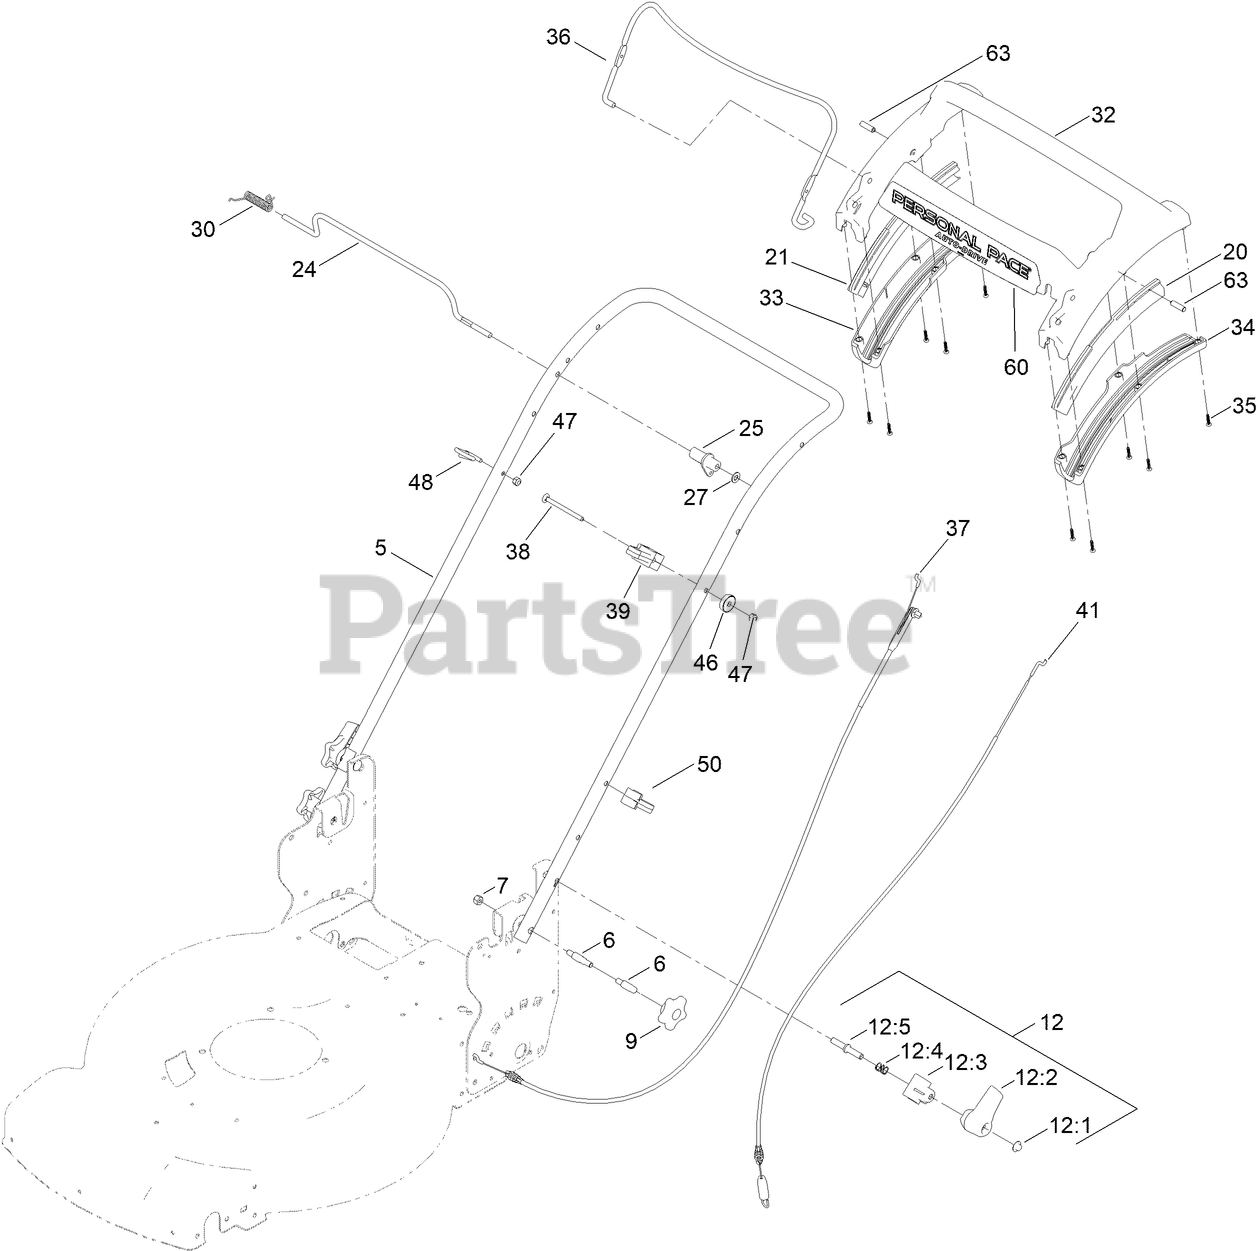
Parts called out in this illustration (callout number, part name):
5	HANDLE-CURVED
6	BOLT-SHOULDER, HANDLE
7	NUT-LOCK, NI
9	KNOB-HANDLE
12	QUICK RELEASE ASM
12:1	NUT-PUSH
12:2	LEVER-RELEASE
12:3	ANCHOR-SPRING
12:4	SPRING-COMPRESSION
12:5	ROD-RELEASE
20	GUIDE-CURVED, LH (RWD)
21	GUIDE-CURVED, RH (RWD)
24	ROD-CONTROL, TRACTION
25	LEVER-TRACTION, RWD
27	WASHER-PLAIN
30	SPRING-TORSION
32	HANDLE-PERSONAL PACE, CURVED
33	BOTTOM-HANDLE, RH
34	BOTTOM-HANDLE, LH
35	SCREW-PPH
36	BAIL-BRAKE
37	CABLE-BRAKE, PP BS
38	SCREW-CARR
39	ANCHOR-CABLE, RWD
41	CABLE-TRACTION, RWD (PP)
46	WASHER-CURVED
47	NUT-LOCK, NI
48	GUIDE-ROPE
50	GUIDE-CABLE
63	PIN-HANDLE, PP
